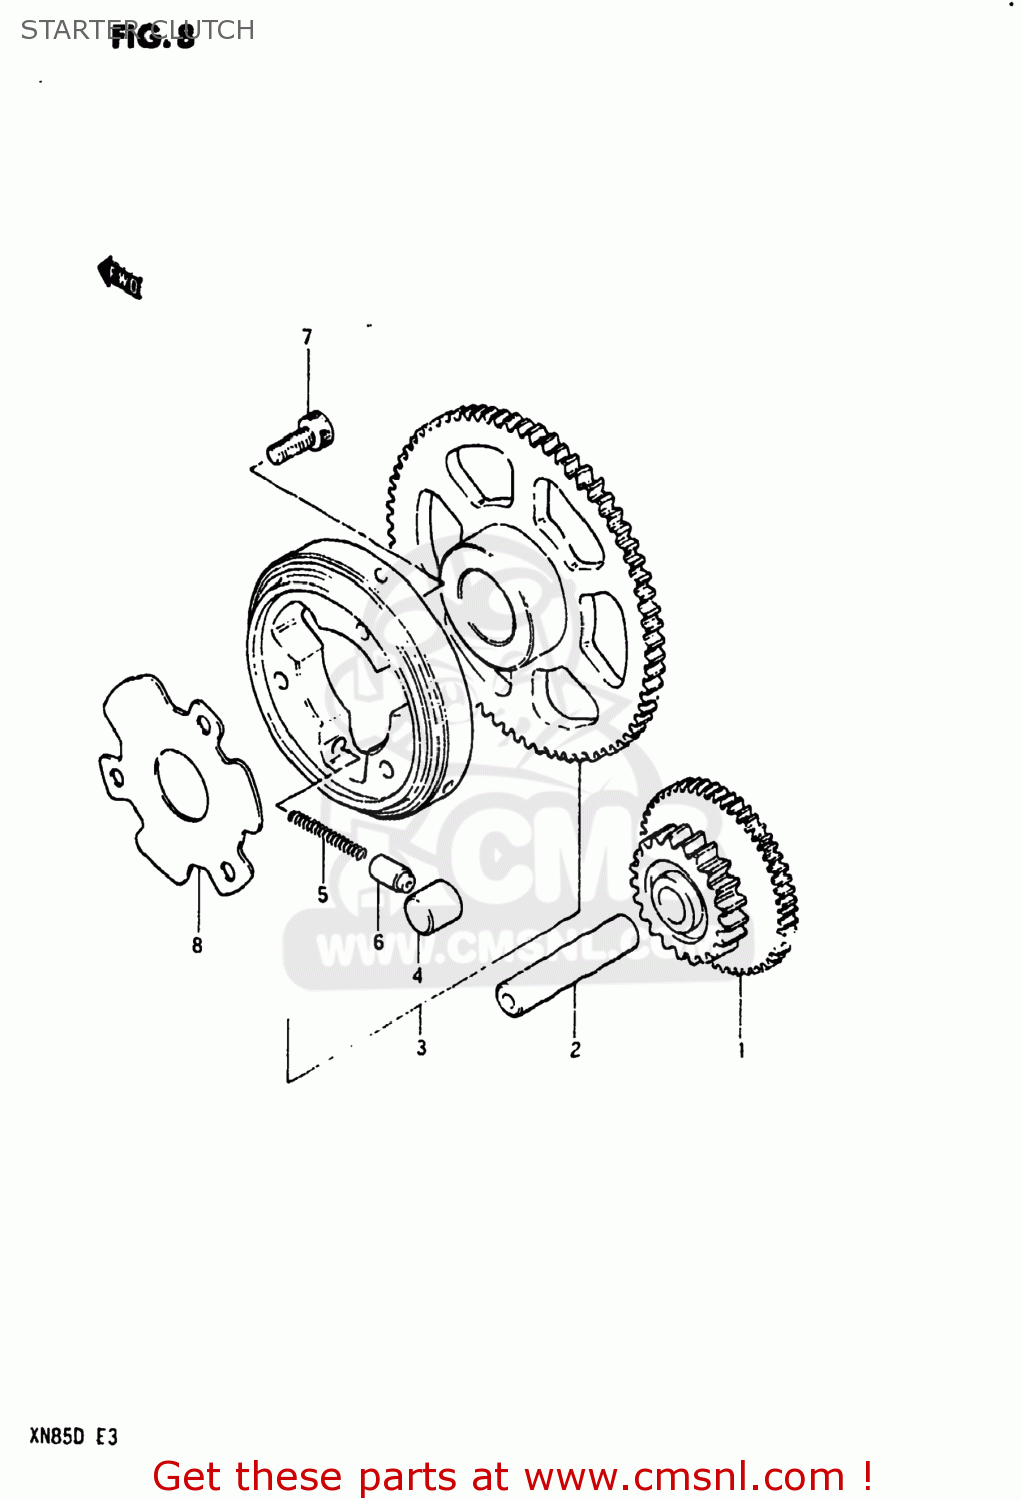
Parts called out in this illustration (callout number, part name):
1	GEAR,STARTER IDLE
2	PIN(7.4X13X56)
3	CLUTCH SET,STARTER
4	ROLLER(15X13)
5	SPRING
6	PIECE,PUSH
7	BOLT
8	SHIM,STARTER CLUTCH HUB
